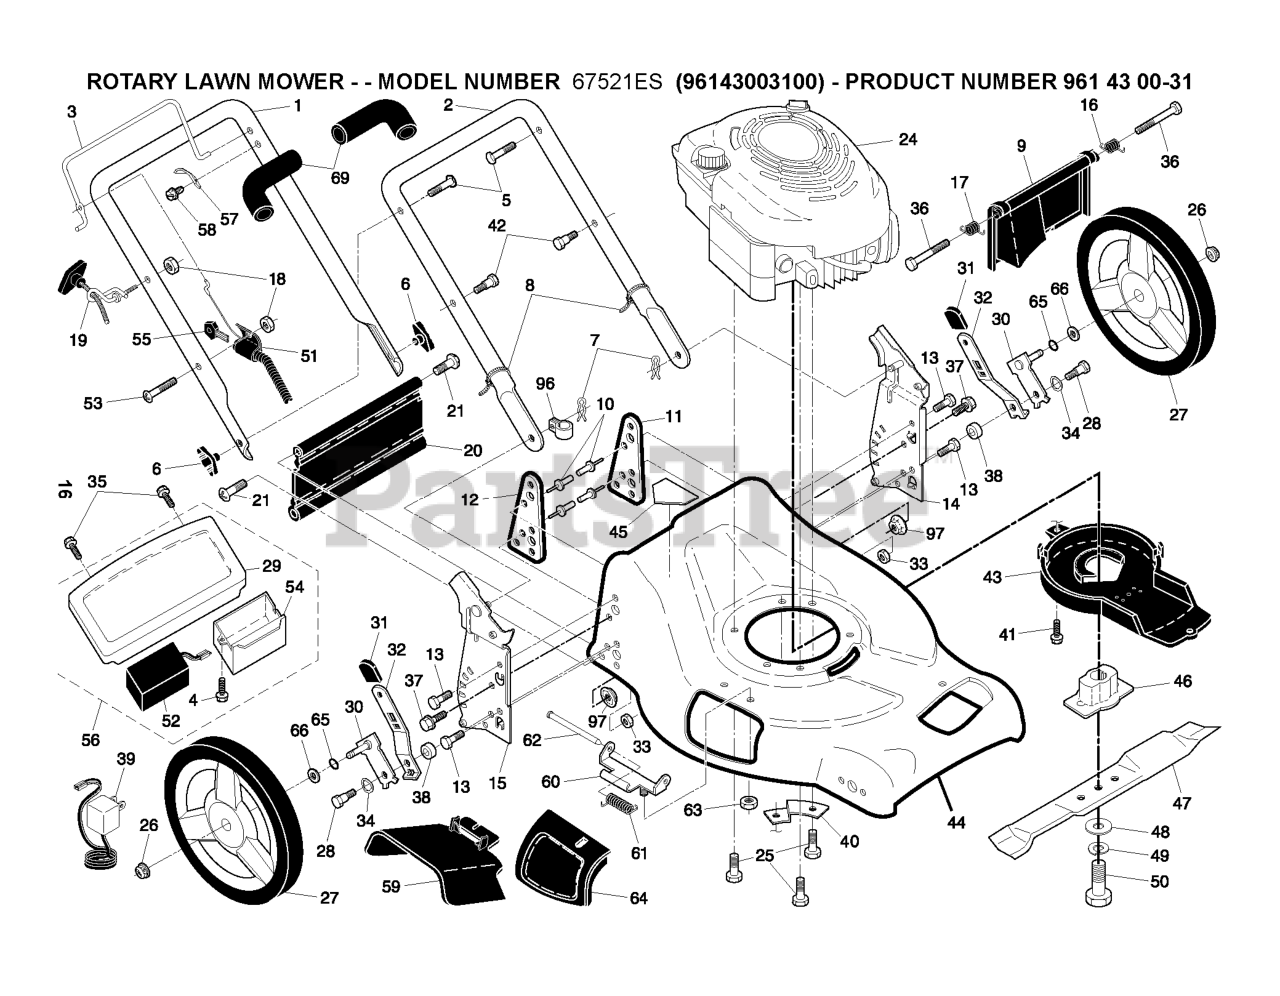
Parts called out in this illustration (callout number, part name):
1	RP HANDLE.ASM.UPPER.W/GRI
2	HANDLE.LOWER.21.FWGD.GREY
3	BAIL.DSTRT.FL.AW.CREAS.ORANGE
4	SCREW.HWH.13-16X.50
5	BOLT, HANDLE 5/16-18X1.75
6	HNDL.KNOB.GRAY
7	HAIRPIN COTTER
8	TIE GUIDE
9	REAR DOOR ASSEMBLY
10	RIVET BLIND
11	SUPPORT BRACKET LH
12	BRACKET.SUPRT.RH.21.FWGD
13	SCREW 14-20 X 5/8
14	BRACKET.ASM.HND.21FG.EZ.L.HW
15	BRACKET.ASM.HND.21FG.EZ.R.HW.P
16	SPRING.REAR.DOOR.EZ.21.LT
17	SPRING.REAR.DOOR.EZ.21.RT
18	NUT
19	RB GUIDE.ROPE.STD.BLK.ZIN WSL
20	SKIRT.REAR.21 FWGD.BLACK
21	HINGE SCREW
25	BOLT 3/8-16X1-1/8
26	NUT.HEX.FLANGE.3/8-16.LOCKNUT
27	WHEEL ASSY
28	SHOULDER BOLT 5/16-18
29	PANEL.TRIM.21.FWGD.ES
30	ARM.ASM.AXLE.REAR.5/9.POS.BZP
31	KNOB.DELUXE.GRAY
32	SELECTOR SPRING
33	NUT.71038.31-18.HEX.NYLOCK
34	WASHER.CURVED.CYLINDRICAL
35	SCREW.PAN.HEAD.#10
37	BOLT
38	SPACER.HEIGHT.ADJUSTER
39	RP CHARGER.BATTERY
40	BRACKET
41	SCREW.HEX.WSH
42	SCREW.SHOULDER.HH.10X.281X.6
43	DEBRIS SHIELD
44	HOUSING.21.FWD.MC.ORANGE.WALK
45	DANGER DECAL
46	RP ADAP.BLDE/PULL
47	BLADE.21.PUSH/RWGD/FWGD
48	WASHER,HARDEN
49	LOCKWASHER
50	SCREW, HEX HD 3/8-24 X 1-3/8
51	KIT.CONTROL.COMBI.KEYW/HARNESS
52	BATTERY WITH AMP CONECTOR AGM
53	SCREW.(COMBINATION CONTROL)
54	BOX.BATTERY.TRIM
55	KEY.MOLDED
56	PANEL.ASM.TRIM/BATTERY.BOX
57	BRACKET UPSTOP
59	DEFLECTOR.CLIPPIN.21.FGD
60	BRACKET.ASM.HINGE.21.FWGD.
61	SPRING.TORSION
62	ROD.HINGE.21
63	LOCKNUT.NYLOC.1/4-20
64	DOOR.MULCH.21.REAR.FWGD
65	O-RING..070X.487.NEOPRENE
66	WASHER.FLAT.1/2
69	GRIP.HANDLE.FOAM.WIDE.(1 SIDE)
96	CLIP.CABLE.BLK
97	NUT.FLANGE.5/16
